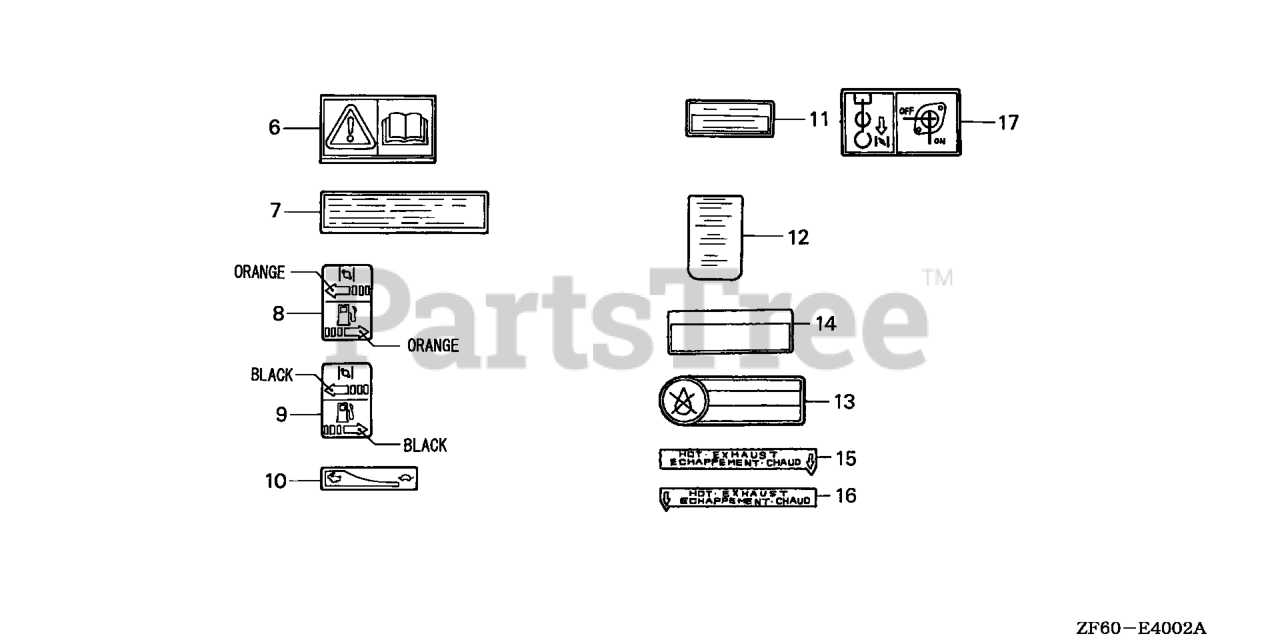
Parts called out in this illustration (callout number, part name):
6	MARK, CAUTION (PICTOGRAPH)
7	LABEL, CAUTION (ENGLISH, ETC.)
8	MARK, CHOKE (EXTERNAL)
9	MARK, CHOKE (BLACK)
10	MARK, THROTTLE INDICATION
11	MARK, OIL ALERT (ENGLISH)
12	LABEL, AIR CLEANER CAUTION
